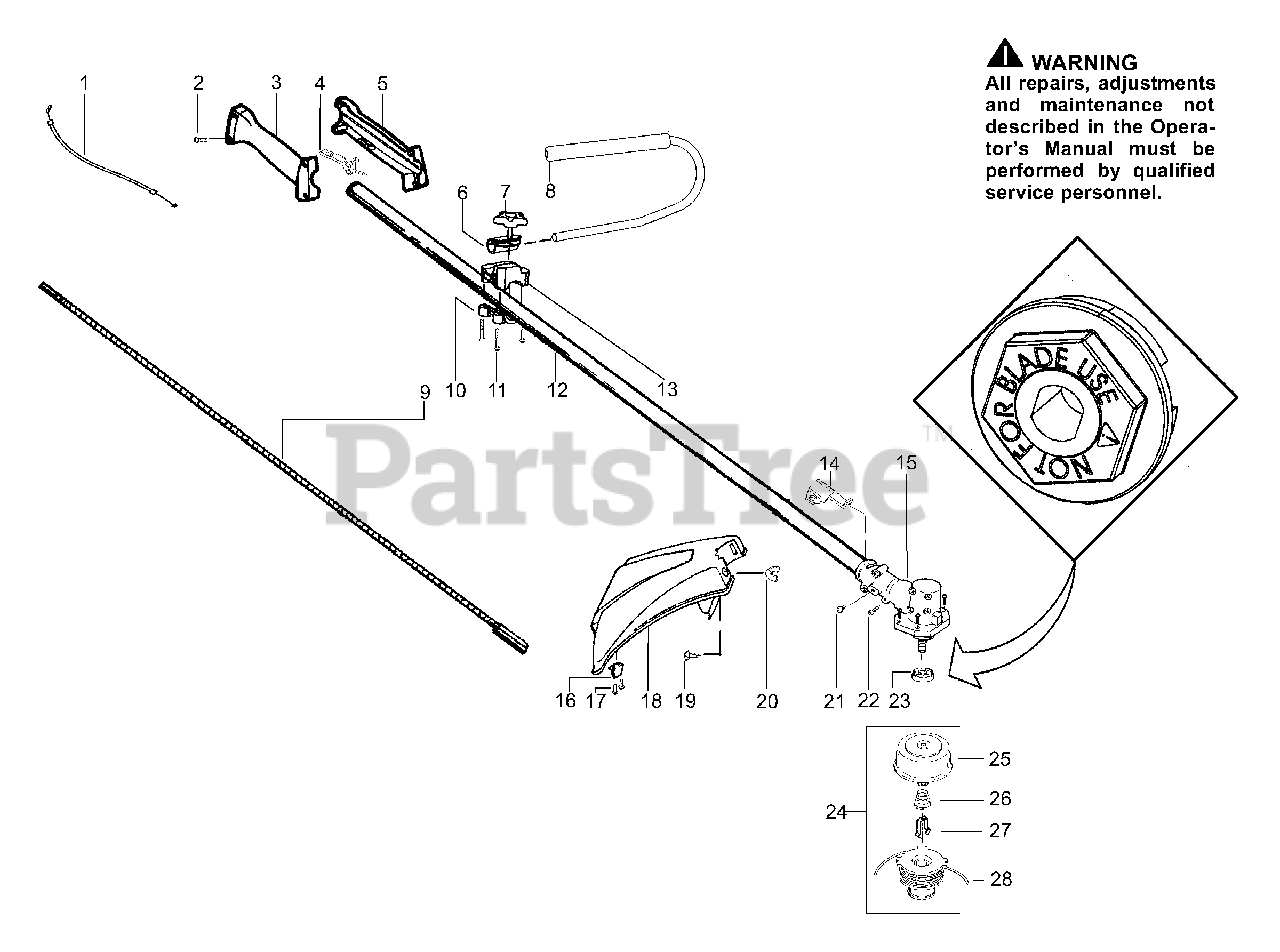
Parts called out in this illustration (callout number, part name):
1	Assy-Throttle cable
3	Throttle Hsg.-Right
4	Trigger-Throttle
5	Throttle Hsg.-Left
6	Clamp-Handlebar
7	Knob
8	Assy.-Handlebar
9	Shaft-Flex
10	Clamp-Tube
12	Assy-Driveshaft
13	Base-Clamp
14	Bracket-Shield
15	Kit-Gearbox
16	Limiter-Line
17	Screw
18	Kit-Shield Ass'y.
20	Wingnut
23	Non-Blade Dust cup
24	Accy.-Cutting Head
25	Assy.-Hub/Arbor (3/8lh , 2x)
26	Spring-Return
27	Retainer-Spool
28	Accy.-Wound Spool
